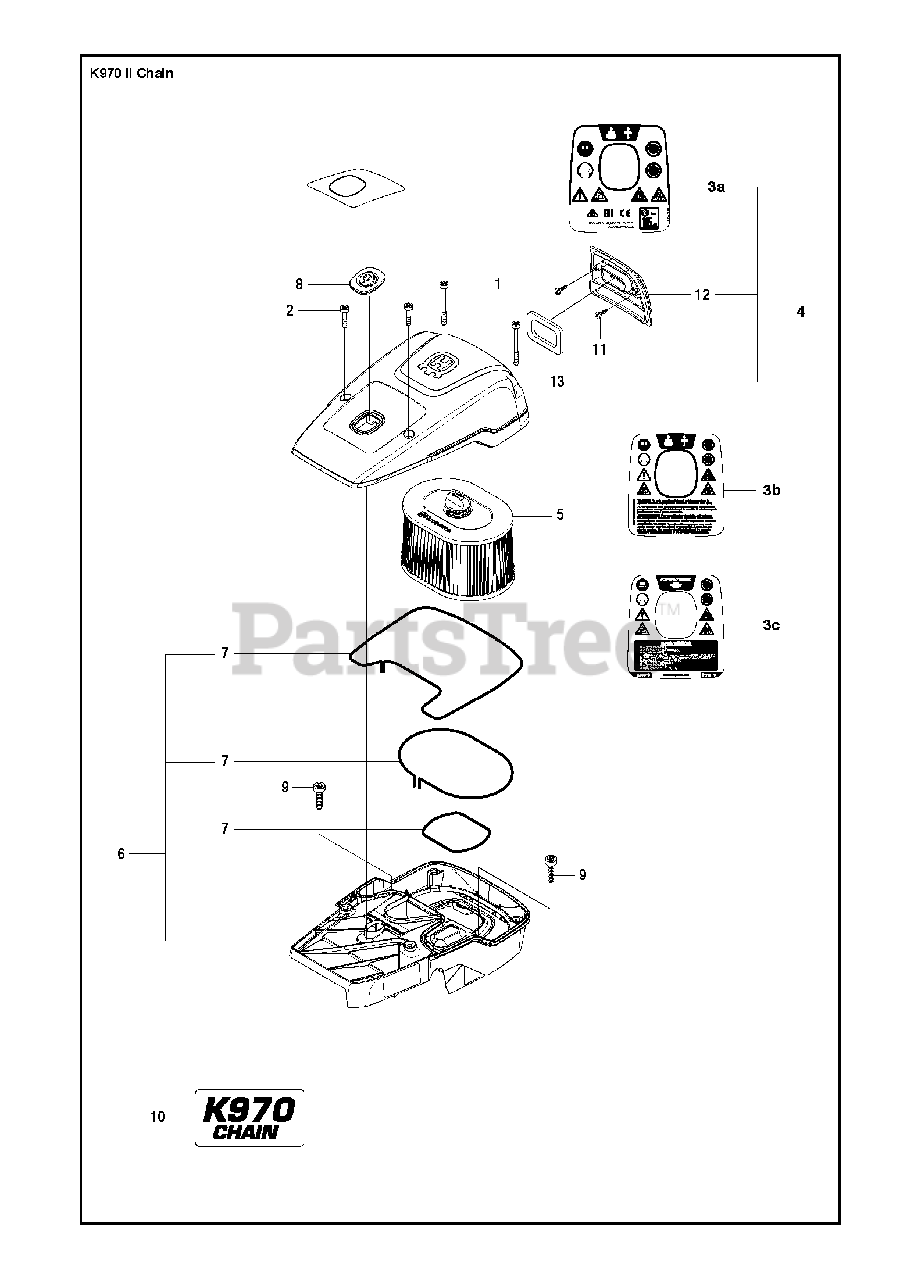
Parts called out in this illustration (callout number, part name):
1	SCREW ITXSCM
2	SCREW ITXSCM
5	AIR FILTER
6	CYLINDER COVER ASSYIncl. 7
7	SEALINGL=1,2 M. Cut to fit
9	SCREW ITXSCM
11	SCREW CRPANT
